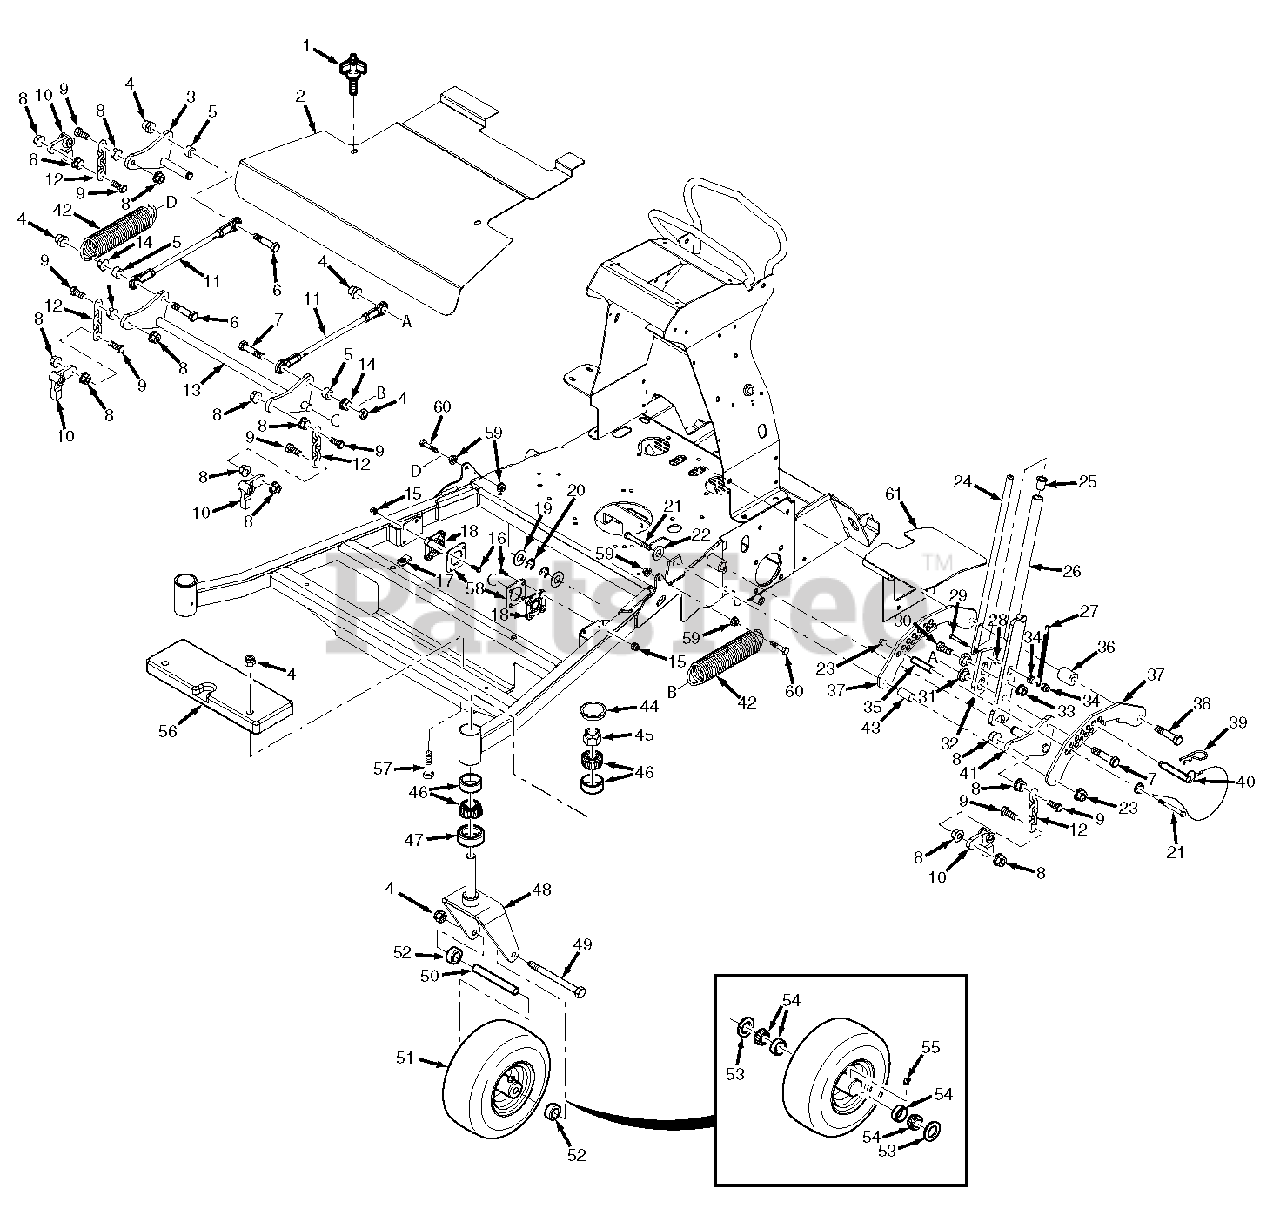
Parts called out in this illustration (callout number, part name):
1	Knob w/Stud
2	Belt Cover w/Decals (52V)
2	Belt Cover w/Decals (61V)
3	Arm Weldment, RH
4	Nut, Elastic Stop 1/2-13
5	Spacer
6	Bolt, Hex Head 1/2-13 x 2-1/2"
7	Bolt, Hex Head 1/2-13 x 3"
8	Nut, Serrated Flange 3/8-16
9	Bolt, Hex Head 3/8-16 x 1-1/2"
10	Lever, Deck Level
11	Linkage, Deck Lift (52V)
11	Linkage, Deck Lift (61V)
12	Chain
13	Deck Lift Weldment (52V)
13	Deck Lift Weldment (61V)
14	Nut, Serrated Flange 1/2-13
15	Nut, Elastic Stop 5/16-18
16	Bolt, Hex Head 5/16-18 x 1"
17	U-Nut, 3/8-16
18	Bearing, Deck Lift
19	Flatwasher, 3/4-.766 x 1.25 x .0598
20	Retaining Ring, .750 "E"
21	Bolt, Hex Head 3/8-16 x 3"
22	Flatwasher, 3/8-.391 x .938 x .105
23	Nut, Elastic Stop 3/8-16
24	Actuator Rod
25	Bearing
26	Handle Weldment, Deck Latch
27	Spring, Deck Latch
28	Spacer
29	Bolt, Hex Head 3/8-16 x 2-1/2"
30	Bolt, Hex Head 1/2-13 x 1-3/4"
31	Bushing, Deck Latch
32	Deck Latch, Outer
33	Nut, Serrated Flange 1/2-13
34	Nut, Elastic Stop 3/8-16
35	Spacer
36	Spacer
37	Bracket, Deck Height (61V)
38	Bolt, Hex Head 1/2-13 x 4-1/2"
39	Hair Pin Cotter
40	Pin Assembly w/Lanyard
41	Arm Weldment, LH
42	Spring, Deck Lift (x2 on 61V only)
43	Spacer
44	Cap, Grease
45	Nut, Elastic Stop 1"-14
46	Bearing w/Race
47	Seal, 2" OD x 1.625 ID
48	Caster Yoke Weldment (52V)
48	Caster Yoke Weldment (61V)
49	Bolt, Hex Head 1/2-13 x 6-1/2" (52V)
49	Bolt, Hex Head 1/2-13 x 9-1/2" (61V)
50	Sleeve, Caster Wheel (52V)
50	Sleeve, Caster Wheel (61V)
51	Caster Wheel Assembly, 11 x 4.0-5 (52V)
51	Caster Wheel Assembly, 13 x 6.5 (61V)
52	Spacer, Caster Wheel
53	Seal
54	Bearing w/Race
55	Grease Fitting
56	Weight
57	Bolt, Hex Head 1/2-13 x 2-3/4" (One Weight)
57	Bolt, Hex Head 1/2-13 x 4-1/2" (Two Weights Installed)
57	Bolt, Hex Head 1/2-13 x 5-1/2" (Three Weights Installed)
58	Reinforcement, Bearing
59	Nut, 3/8-16 Serrated Flange
60	Bolt, Hex Head 3/8-16 x 1-1/2" Grade 8
61	Fender Weldment
